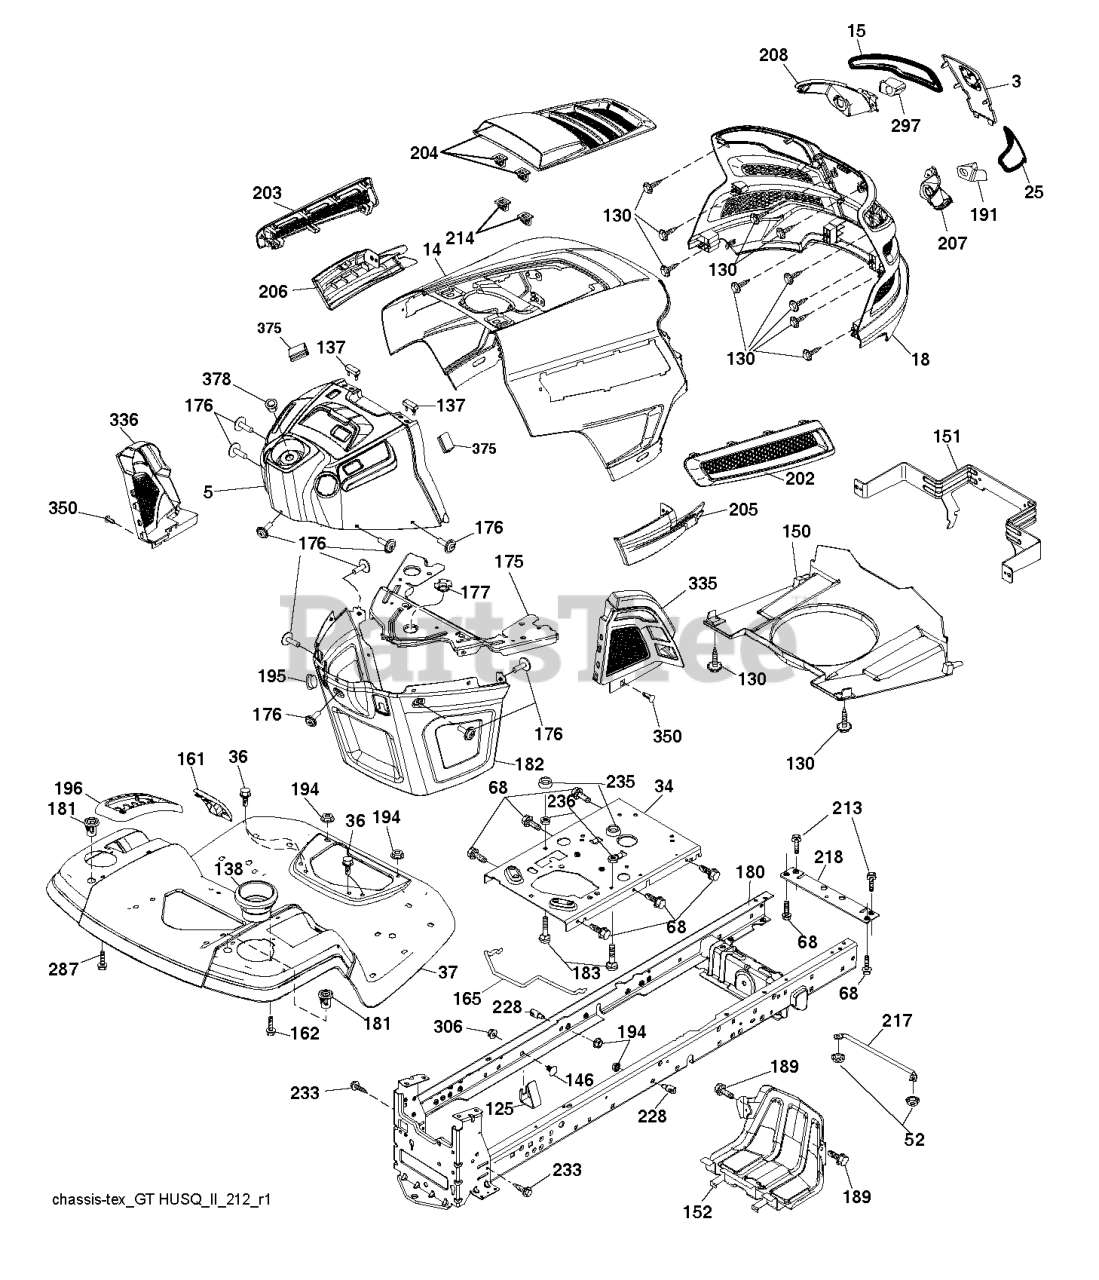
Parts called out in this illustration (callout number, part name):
3	APPLIQUE.SUBASM.GT.HUSQ.II
5	DASHBOARD.UPPER.ASM.GT2.498
14	HOOD.ASM.HUSQVARNA.GT.TEX.ORAN
15	LENS.HEADLIGHT.LH.GTII.2011
25	LENS.HEADLIGHT.RH.GTII.2011
34	PLATE.ENGINE.WELDED.CHASSIS
36	SCREW 5/16"
37	FENDER.ERGO.LT.W/CPH.W/FW.ORNG
125	CLIP.FUEL.LINE
137	BUMPER DASH
138	HOLDER.CUP.LT.GREY
146	BOLT.RDHD.SHT.SQNK.3/8-16X5/8
150	AIR.DUCT.GTV.BLACK
151	BRACKET.PIVOT.HOOD.GT.HUSQ.II
152	SHIELD.BROWNING.PNT.GT.V2
161	WINDOW.FUEL.LT.HUSQ.TEX.498
165	SUPPORT.TANK.REAR.W/TEX
175	PLATE.PNT.CROSSMEMBER.HUSQ/PRE
176	SCREW.#10-24X5/8.RN.QU
177	BUSHING STEERING
180	CHASSIS
181	BUSHING.MNT.FEND.CRGO.TEX.49
182	DASH.LOWER.COMMON.12V.ADAPTOR
189	SCREW
191	INSERT.REFLECTIVE.RH.HUSQ.GTII
195	PLUG.HOLE.DASH.LOWER.12V.BLK
196	DECKLFT.CONSOL FULL ASSM GREY
202	VENT.SIDE.RH.GT.HUSQ.II.
203	VENT.SIDE.LH.GT.HUSQ.II.498
204	VENT.TOP.ASM.HUSQ.GT2
205	SIDE.TRIM.RH.GT.HUSQ.II
206	SIDE.TRIM.LH.GT.HUSQ.II.GRAY
207	HEADLIGHT.CUP.BEZEL.HUS.GT2.RH
208	HEADLIGHT.CUP.BEZEL.HUS.GT2.LH
213	SCREW HEXAGON HEAD SCREW 5/16-
214	CLIP.RETAINER.TINNER.
217	ROD.PIVOT.HOOD
218	X-PIECE.HOOD.STOP.NON/
228	STUD.W/"D"ANTI-ROTATION
233	BOLT.SHOULDER
236	NUT.CENTERLOCK.5/16-
287	SCREW 1/4X20
297	INSERT.REFLECTIVE.LH.HUSQ.GTII
306	NUT LOCK FLG 3/8-16 UNC
335	COVER.LOWER.DASH.RH.BLACK
336	COVER-LH.LOWER.DASH.GT2.BLACK
350	CLIP.X-MAS.TREE
375	BUMPER CLIP-ON. DASH 1"
378	BUSHING FLANGE; PLASTIC
